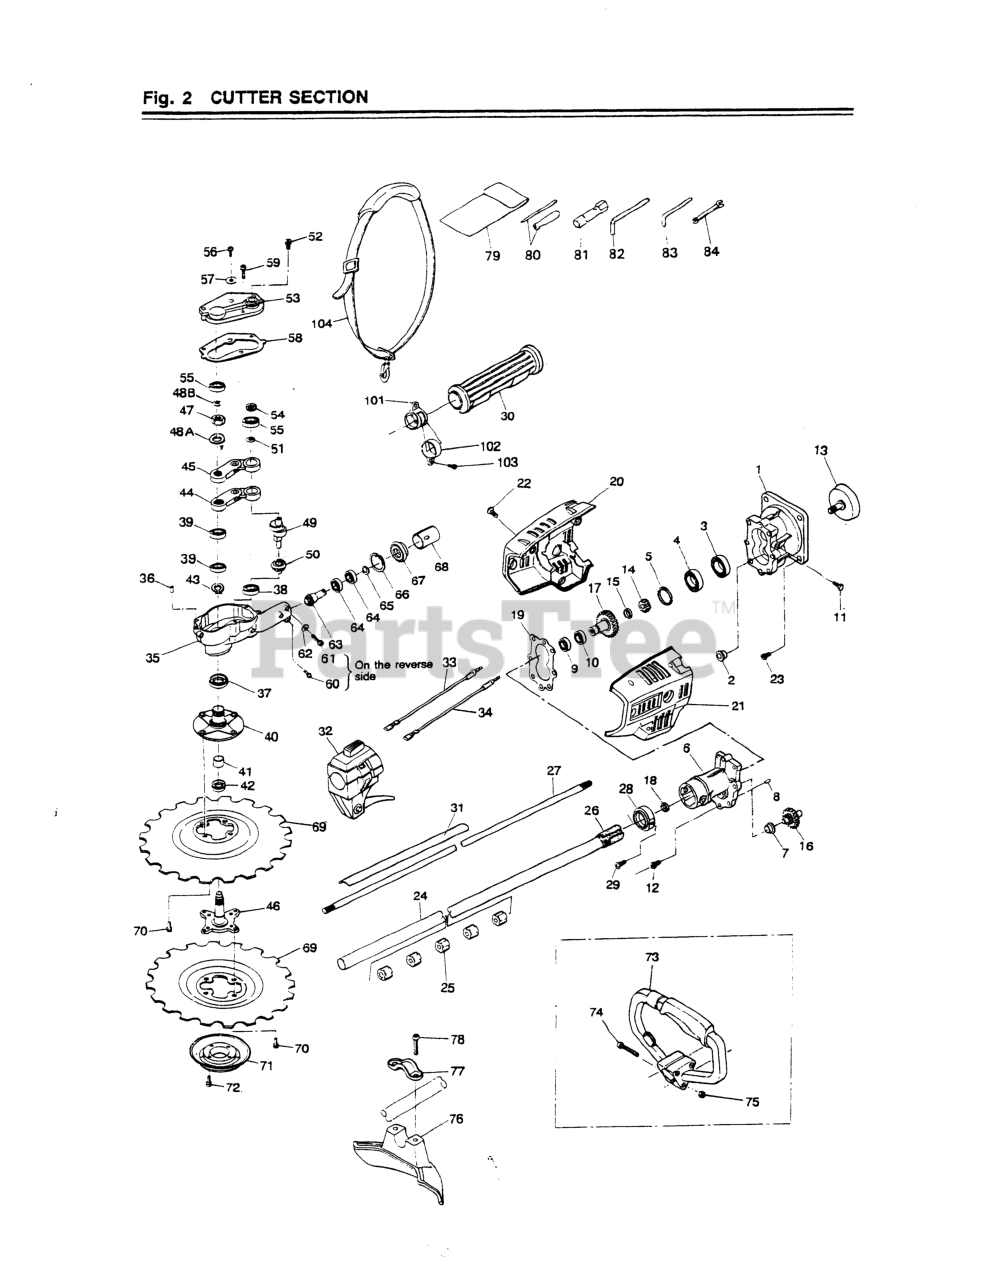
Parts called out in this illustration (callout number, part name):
1	CASE-R-C
3	BEARING
4	BEARING
5	RING, SNAP, M28 x 1.2
6	CASE-P-C
8	PIN, DOWELL
9	BEARING
10	BEARING
11	BOLT, M6 x 8
12	BOLT, M5 X 20
13	DRUM
14	GEAR, PINION
15	RING, SNAP
17	GEAR, WHEEL
27	SHAFT
28	CAP
29	SCREW, M5 X 10
33	CORD-A, BLACK
34	CORD-B, RED
36	PIN, DOWELL
37	SEAL, OIL
39	BEARING
40	SHAFT, OUTER-C
41	BUSHING
42	SEAL, OIL
43	RING, SNAP, M20 x 1.2
44	LINK-L-C
46	SHAFT, INNER
48A	SHIM, 0.3t
48A	SHIM, 0.2T
50	GEAR
51	WASHER, M8 x 1.2
52	BOLT
54	SEAL, OIL
55	BEARING (RPLS. T4001-31340)
56	SCREW, M6 x 10
57	GASKET
58	GASKET
59	BOLT, M5 x 20
60	BOLT, M5 X 25
61	BOLT, M5 x 14
63	PINION
64	BEARING (RPLS T3403-13510)
65	RING, SNAP
66	RING, SNAP, M26 X 1.2
67	PACKING
70	BOLT, M6 x 8
74	SCREW, M5 x 30(RPLS 0263-00530
75	NUT, M5 X 4
77	CLAMP (REPLACES 5807-24120)
78	BOLT, M6 x 1.30
80	SCREWDRIVER
82	WRENCH (TOOL)
83	WRENCH (TOOL)
84	SPANNER, 8 X 10 (RPLS 2540- )
101	HANGER (USE -18101)
103	SCREW, M5X20 (RPLS.1400-75510)
